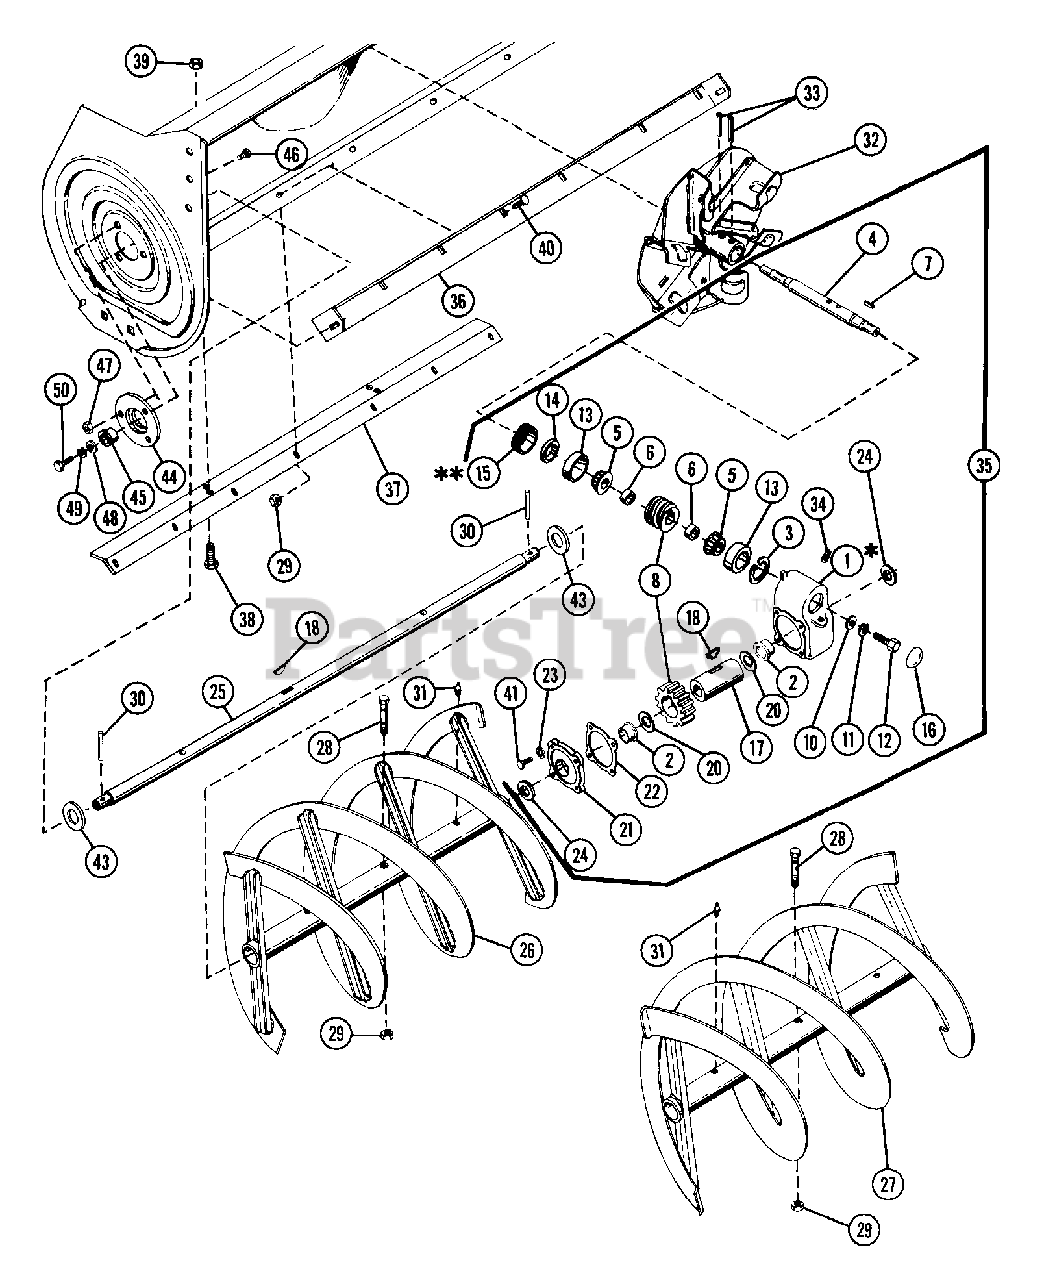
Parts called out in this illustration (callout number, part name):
1	GEAR CASE - CAST IRON
2	BSHG-FLG .683X1.87X1.68X2.250
3	RG-RTNG-INT 1.781X.062
4	WORM SHAFT
5	BRG-CONE .750X.61
6	BSHG, SPCR .755X1.12X.50 PM
7	KEY-SQ .188X1.0X.188 SAE 8630
8	WORM & GEAR SERVICE ASSEMBLY
9	WSHR-FL-STL .38X.875X.083 PL
10	WSHR-FL-STL .328X1.0X.094
11	WSHR-LK .312X.097 PL HVY
12	BLT-HEX .31-18X.75 PL GR2
13	BRG-CUP 1.781X.475
14	SEAL 1.000X1.312X.150
15	ADJUSTMENT PLUG - 1" SHAFT
16	DUST CAP
17	GEAR CASE SHAFT
18	KEY-WDRF .25X.875X.375 SAE A
20	WSHR-FL-STL 1.625X2.500X.012
21	GEAR CASE COVER
23	WSHR-LK-EXT. 250 ID
24	SEAL 1.625X2.125X.250
25	SHAFT, 36" RAKE - 1.00 DIA.
26	RAKE, RIGHT-36"(1ID X 15.75OD)
27	RAKE, LEFT-36"(1"ID X 15.75OD)
28	SHEAR BOLT SERVICE ASSEMBLY
29	NUT-LK .312-18 GR A PL
30	PIN-ROLL .188X1.50
31	SPIN DRIVE ZERK FITTING
32	FAN - 14"
33	PIN-ROLL .313X1.75
34	PIPE PLUG
35	GEAR CASE - 40" - CAST IRON
36	SCRAPER BLADE 36"
37	BLADE BRACE
38	BLT-HEX .38-16X.75 PL GR5
39	NUT-LK TOP .375-16 GR C YWZC
40	BLT-RDHDSQNK .31-18X.75 GR5 PL
41	BLT-HEX .25-20X.75 PL GR2
43	WSHR-FL-STL 1.010X1.505X.062PL
44	BEARING SUPPORT
45	BSHG-FLG 1.000X1.12X.62X1.50BR
46	SCR-SLTR-SERNK .25-20X.62 PL
47	NUT-LK-FLG .250-20 PL
48	WSHR-FL-STL.312X.734X.065PL
49	WSHR-LK .500X.151 HVY PL
50	BLT-HEX .50-13X1.00 PL GR2
